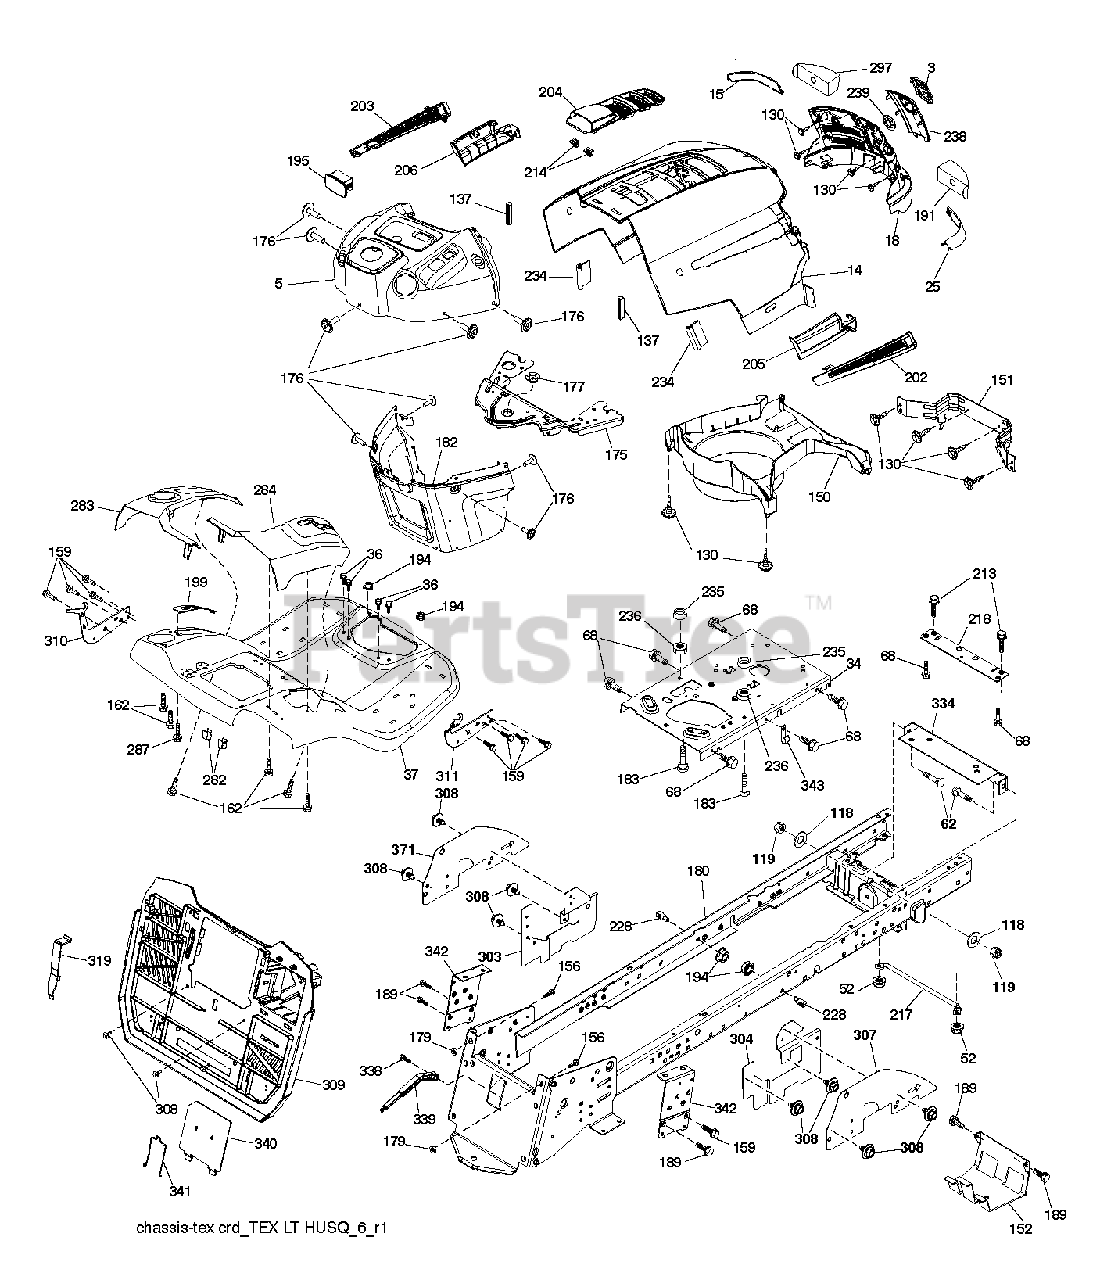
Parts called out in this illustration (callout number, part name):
3	LOGO.HUSQ.GT.LT.CROWN.H
5	DASH.UPPER.HUSQ.LT.MAN.NO-CHK
14	HOOD.HUSQVARNA.LT.ORANGE
15	LENS.HUSQVARNA LT.RH
18	GRILLE.SVC.HUSQVARNA.GREY
25	LENS.HUSQVARNA LT.RH
34	PLATE.ENGINE.10GA.CRD.GENII
36	SCREW 5/16"
37	FENDER.TEX.SRD.CRD.FRN.GUARDS
52	LOCKNUT
62	BOLT D
68	SCREW LT
118	WASHER
130	SCREW.#10 X 0.750.BOS
137	BUMPER DASH
151	BRACKET PIVOT
152	SHIELD.BROWNING.W/TEX
159	SCREW, 3/8-16X3/4
162	SCREW.HI-LO.CONSOLE
175	CROSSMEMBER
176	SCREW.#10-24X5/8.RN.QU
177	BUSHING STEERING
180	CHASSIS WLDT TEX CRD
182	DASH.LOWER.PREDATOR LT
183	BOLT.5/16-18X1-1/4 FULL THD
189	SCREW
191	INSERT.REFLECTIVE.RH.
194	NUT LOCK HEX FLANGE 5/16-18
195	PLUG.TEX.DASH.SVC.MINDER.GREY
199	PLATE DECK LIFT
202	VENT.SIDE.HUSQVARNA.LT.RT
203	VENT.SIDE.HUSQVARNA.LT.LFT
204	SUBASM.TOP.VENT.HUSQ.LT
205	SKIRT.SIDE.HUSQVARNA.LT.RT
206	SKIRT.SIDE.HUSQVARNA.LT.LEFT
213	BOLT
214	CLIP.RETAINER.TINNER.
217	ROD.PIVOT.HOOD
218	X-PIECE.HOOD.STOP.NON/
228	STUD.FASTNER.W/ANTI-ROTATE
234	BUMPER.HOOD.TEX.HUSQVARNA
235	SPACER FENDER
236	NUT.CENTERLOCK.5/16-
238	TRIM.HUSQ LT.668
282	CLIP.RETAINER.CONSOLE.LT.HUSQ
283	CONSL.DECKLIFT.LH.SRD.TEX.CRD
284	CONSL.SHIFT.GEAR.RH.SRD.GREY
287	SCREW 1/4X20
297	INSERT REFLECTIVE
303	SHIELD.LWR.LH.LT.30"CRDSRD.PNT
304	SHIELD.LOWER.RH.CRD.GEN.PNT
307	SHIELD.UPPER.CRD.SRD.ISO
308	BOLT, 5/16-18 X 1 3/4
309	BACKPLATE.TEX.CRD
310	LH.ADJUST.HANGER.BRACKET.ASM
311	RH.ADJUST.HANGER.BRACKET.ASM
319	BRACKET.ACTUATOR.BAGGER.SRD
334	BRACKET.ENGINE
338	BOLT BOLT SHOULDER
339	LEVER LEVER BAGGER
340	DOOR.PNT.BATTERY.TRY.TEX.CRD.
341	LATCH
342	SUPPORT SUPPORT FENDER
343	CLIP CLIP
371	SHIELD.UPPER.CRD.SRD.ISO
